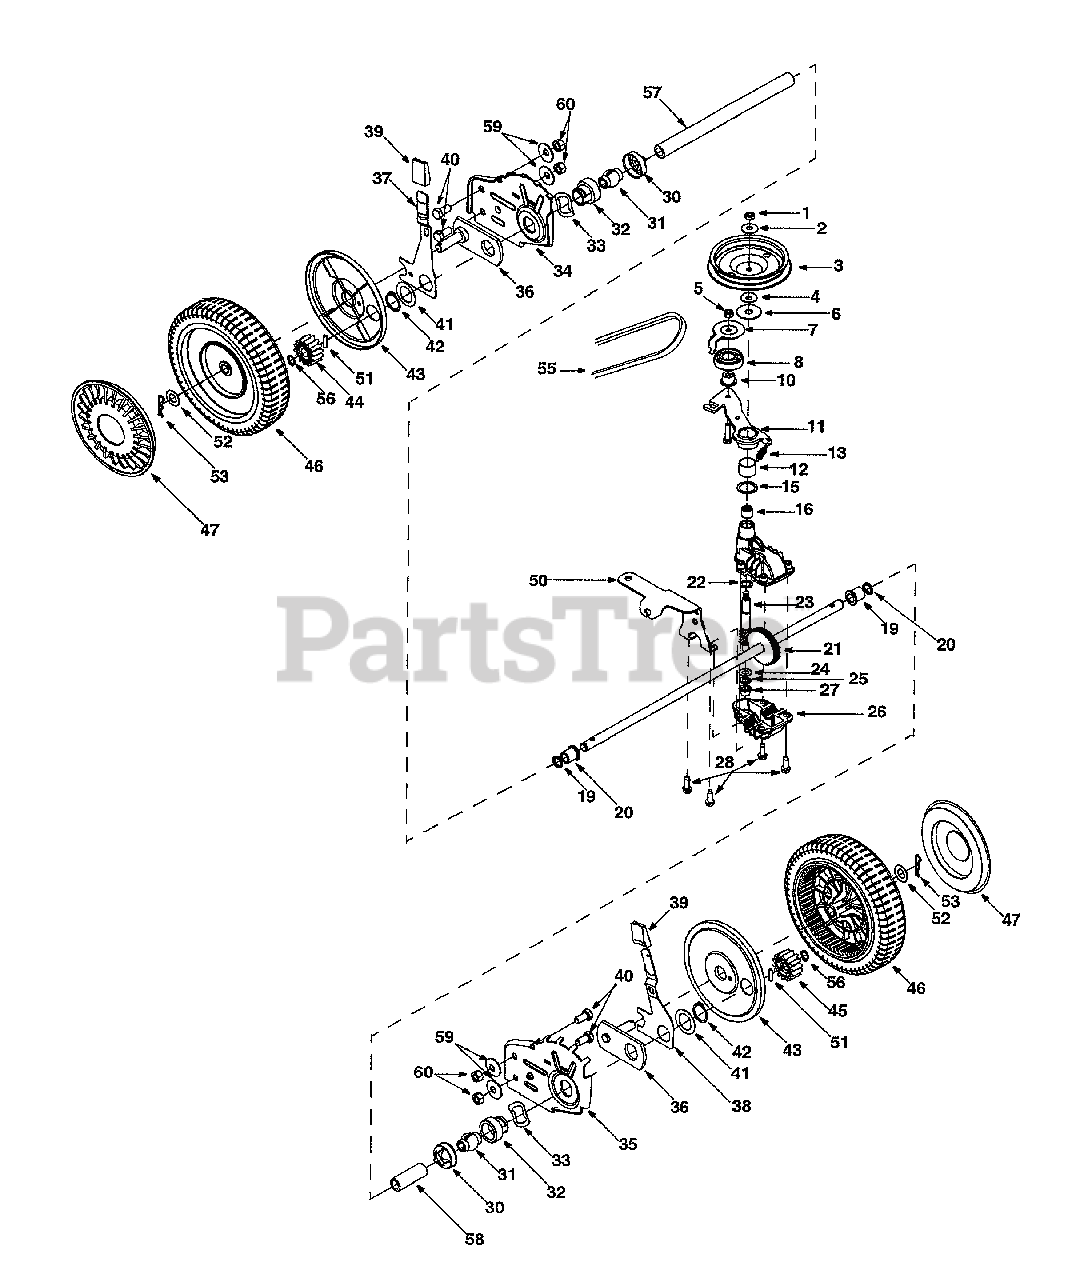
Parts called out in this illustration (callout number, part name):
1	Hex Jam Nut 5/16-24
2	Bell Washer .325 x .930 x .045
3	Pulley, 3.82 x .313 x .68
4	Bell Washer .325 x .930 x .045
5	Lock Nut 1/4-28
6	Flat Washer .442 x 1.38 x .060
7	Belt Keeper
8	Ball Bearing
10	Flange Spacer
11	Idler Bracket Assembly
12	Bearing Sleeve
13	Flat Washer .504 x .700 x.030
15	Flat Washer .865 x 1.145 x .030
16	Needle Bearing .438 x .625 x .500
19	Oil Seal .500 x .687 x .094
20	Flange Bearing
21	Output Shaft
22	Flat Washer .504 x .700 x .030
23	Pinion Shaft 10T
24	Thrust Washer .375 x .70 x .030
25	Thrust Washer .388 x .625 x .062
26	Lower Housing
27	Flange Bearing .378 x .531 x .370
28	Hex Screw w/Washer 1/4-20 x .750
30	Bearing Retainer
31	Bearing Sleeve .50 I.D.
32	Bearing Support
33	Wave Washer 1.5 x 1.0 x .029
37	RH Front Lever
38	LH Front Lever
39	Knob
40	Hex Cap Screw 3/8-16 x .75
41	Washer DD 1.5" O.D.
42	Snap Ring 1.0 dia.
43	Wheel Dust Cap
44	Gear 14T R.H.
45	Gear 14T L.H.
46	Wheel, 8x2 x 1.75
47	Hubcap: Gray
50	Cable Idler Bracket
51	Dowel Pin
52	Flat Washer 1/2 x 1.00 x .063
53	Cotter Pin .08 x 1.42
55	Belt
56	Snap Ring
57	Slev. Spacer
58	Slev. Spacer
59	Bell Washer
60	Hex Nut 3/8-16
